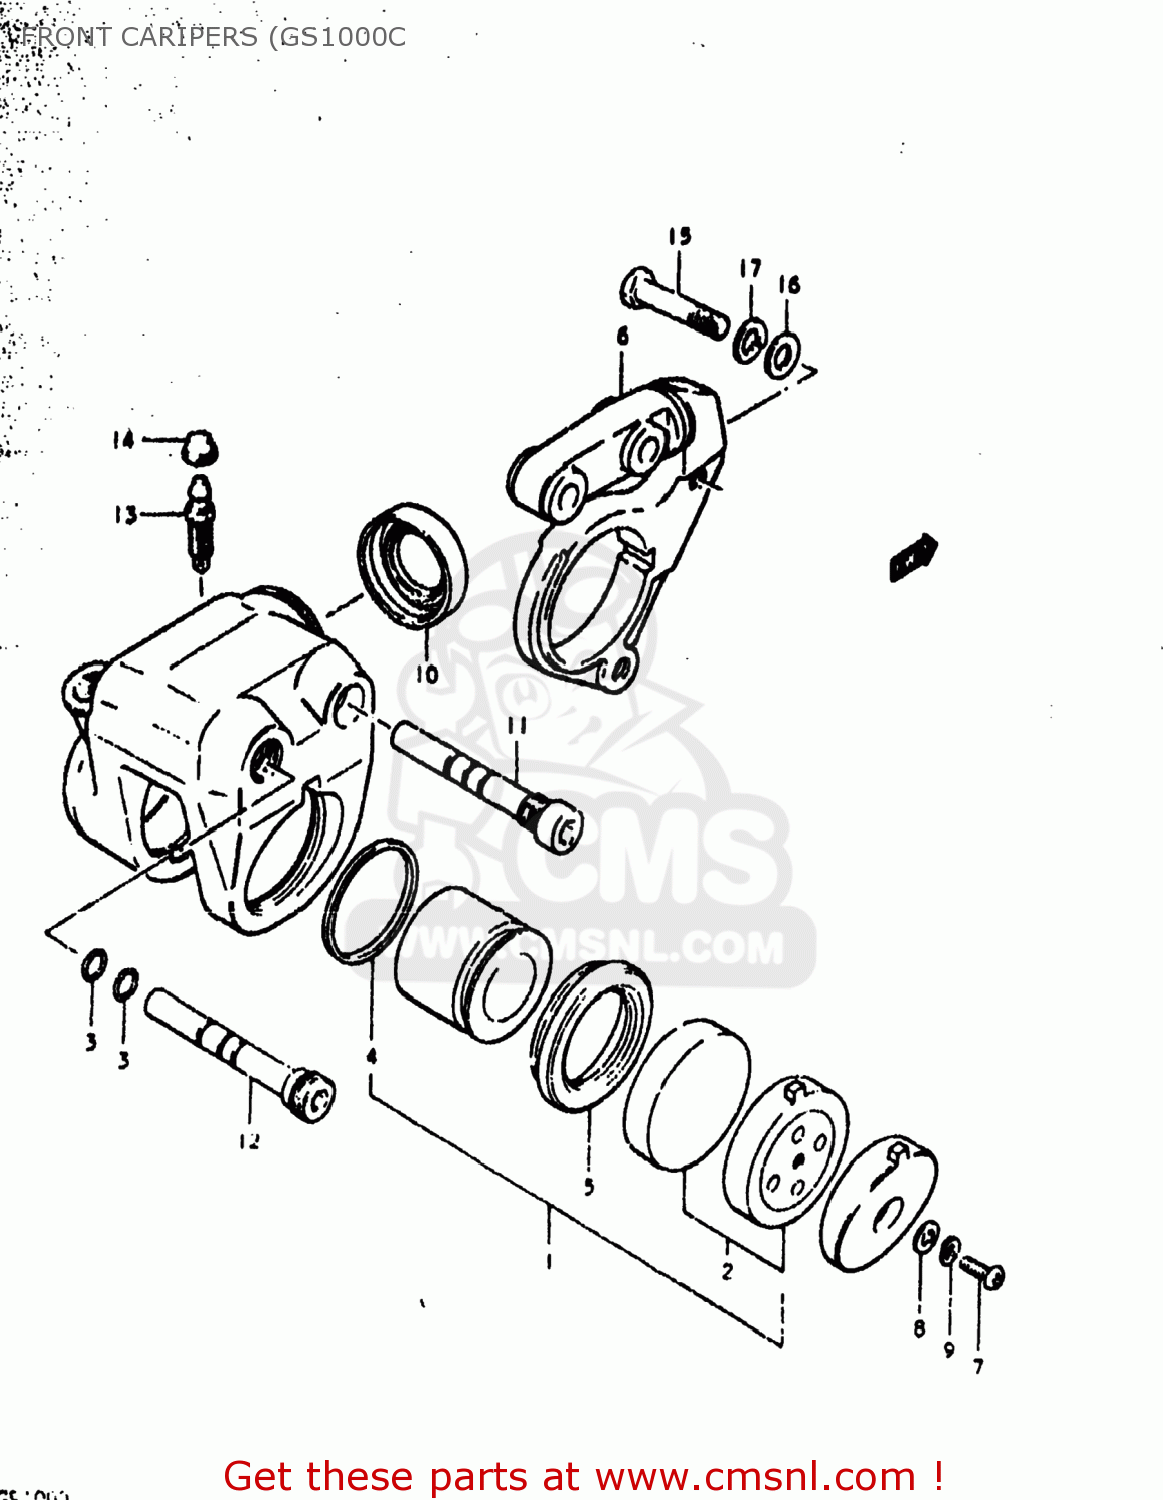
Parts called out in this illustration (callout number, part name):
1	PAD SET
2	PAD SET (MCA)
3	O RING,AXLE CALIPER
4	SEAL,PISTON
5	BOOT,PISTON
6	HOLDER,CALIPER
7	SCREW
8	WASHER
9	LOCK WASHER
10	BOOT,HOLDER
11	AXLE,CALIPER
12	AXLE NO.2
13	BLEEDER
14	CAP,BLEEDER PL
15	BOLT
16	WASHER
17	LOCK WASHER
